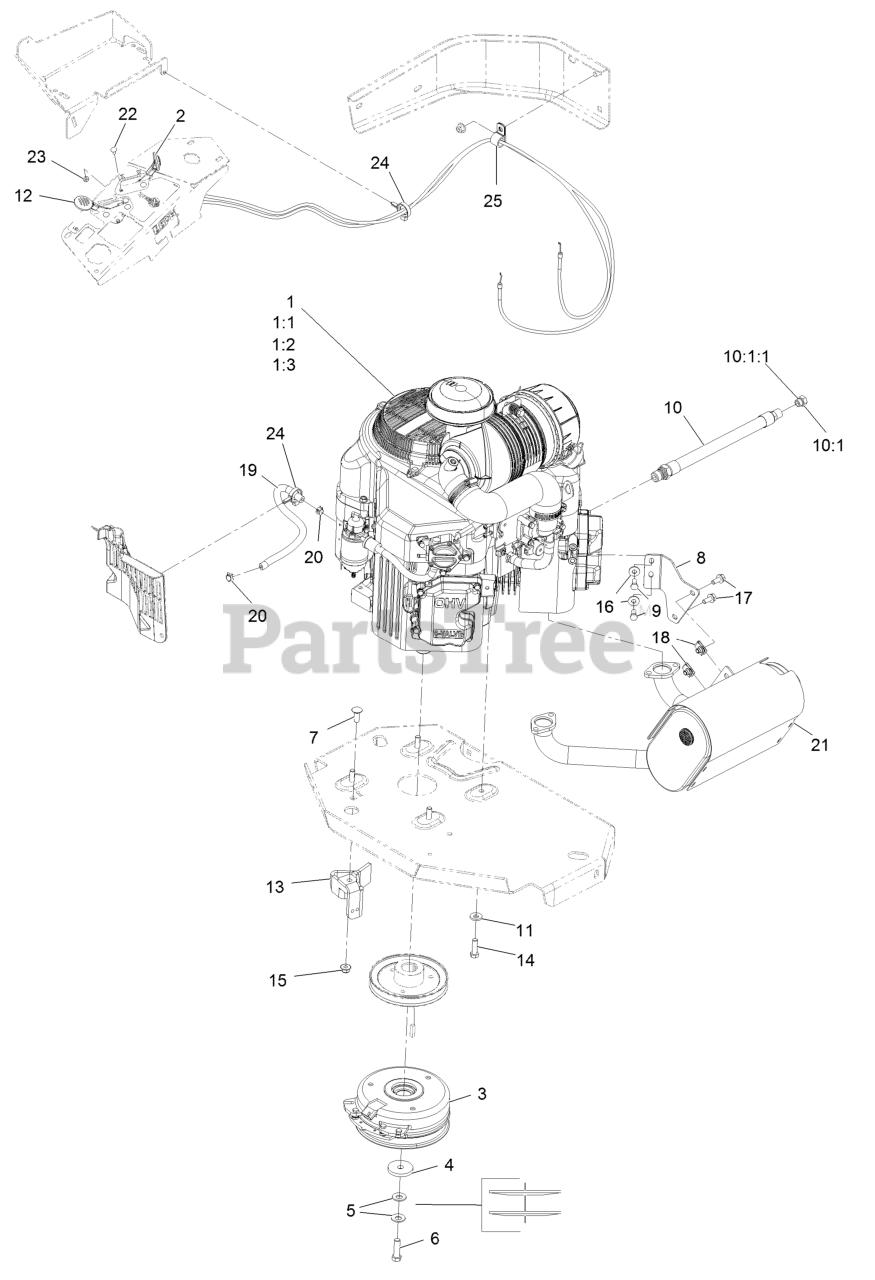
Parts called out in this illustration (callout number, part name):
1:1	Kawasaki 49065-7007 Engine Oil Filter
1:2	Kawasaki 11013-7044 Engine Air Filter
1:3	Kawasaki 11013-7045 Safety Filter
2	Control, Choke
3	Clutch Kit
4	Washer-Clutch
5	Washer-Spring
6	Screw-HH
7	Screw-CARR
8	Bracket-Muffler
9	Screw-HH
10	Engine Oil Drain Hose ASM
10:1	Plug-HH
10:1:1	O-Ring
11	Washer-Belleville
12	ASM,Throttle Cable
13	Clutch-Anchor
14	Screw-HH
15	Nut-HF, NI
16	Washer-Spring
17	Screw-HHF
19	Hose-Fuel
20	Clamp-Hose
21	Muffler
22	Bolt-CARR
23	Nut-Lock, NI
24	Clamp-Hose
25	Clip-Loom
